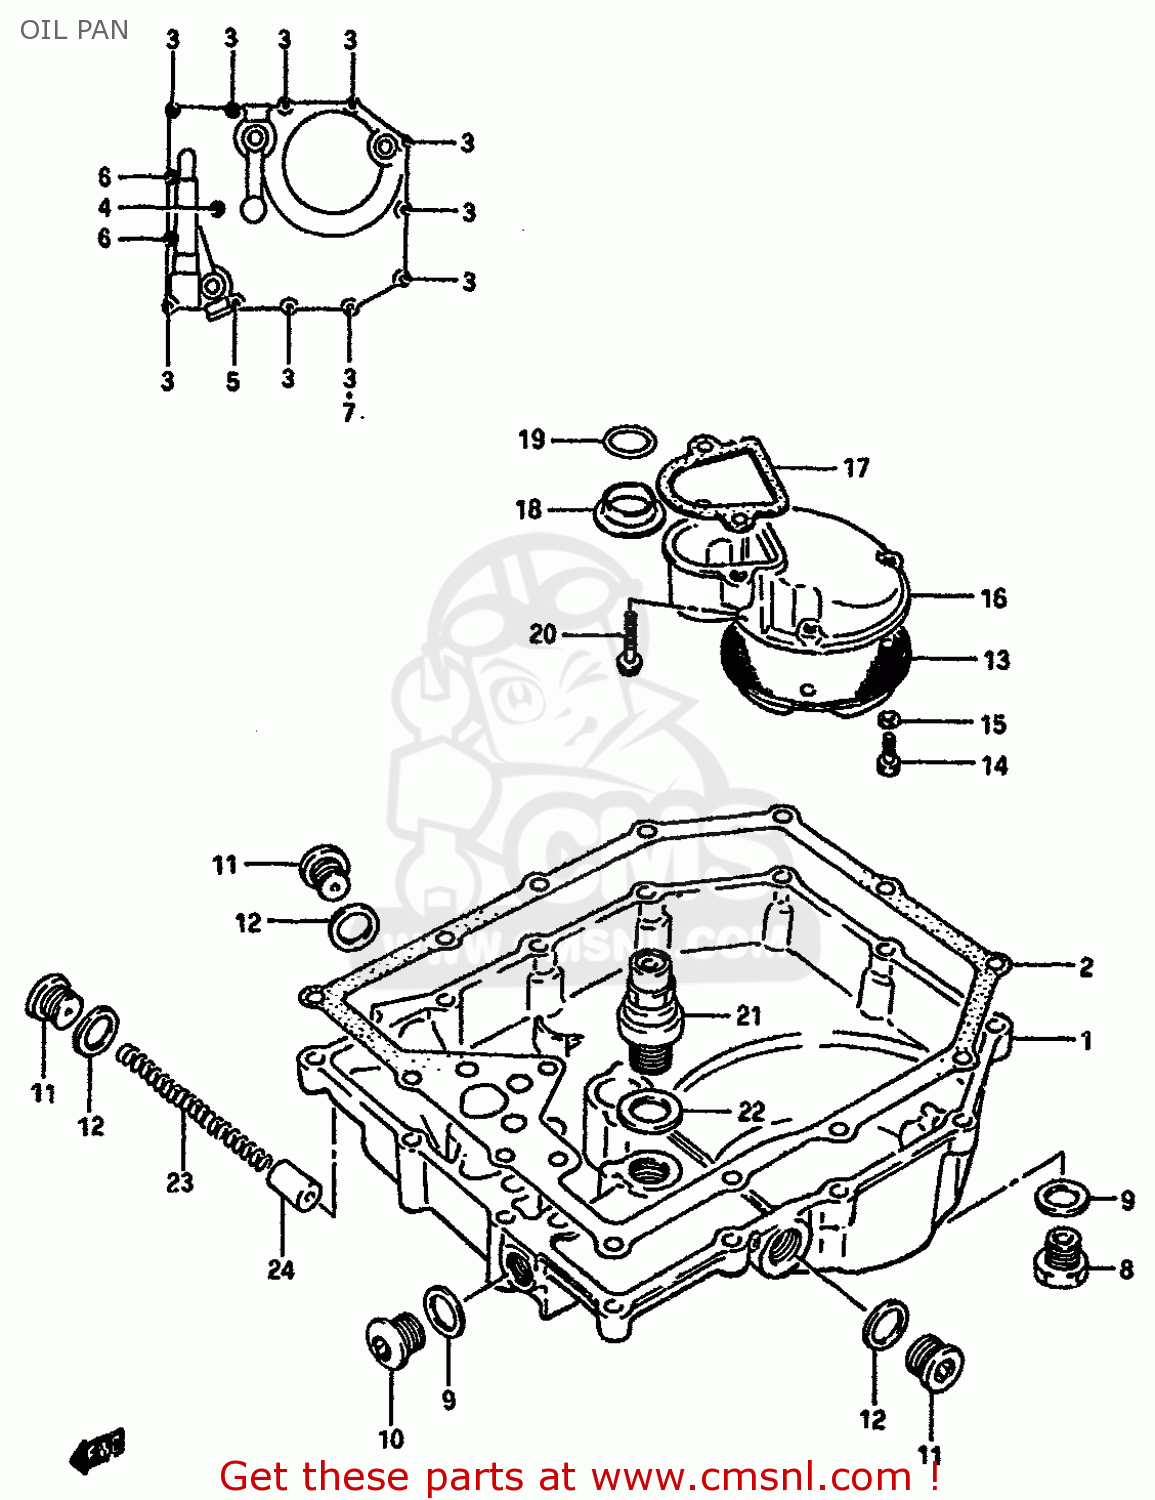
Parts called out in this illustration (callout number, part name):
1	PAN,OIL
2	GASKET,OIL PAN (NAS)
3	BOLT
4	BOLT
5	BOLT
6	BOLT
7	GASKET(5.8X11X1.2) (NAS)
8	PLUG
9	GASKET(14X19.2X2) (NAS)
10	PLUG
11	PLUG
12	GASKET
13	STRAINER,ENGINE OIL
14	BOLT
15	WASHER,LOCK
16	PROTECTOR,OIL STRAINER
17	GASKET,OIL STRAINER PROTECTOR (NAS)
18	GASKET,OIL OUTLET (NAS)
19	O RING(D:3.2,ID:17.8)
20	BOLT
21	VALVE ASSEMBLY,OIL RELIEF
22	GASKET(16X22X2) (NAS)
23	SPRING
24	PLUNGER,OIL CONTROLL
